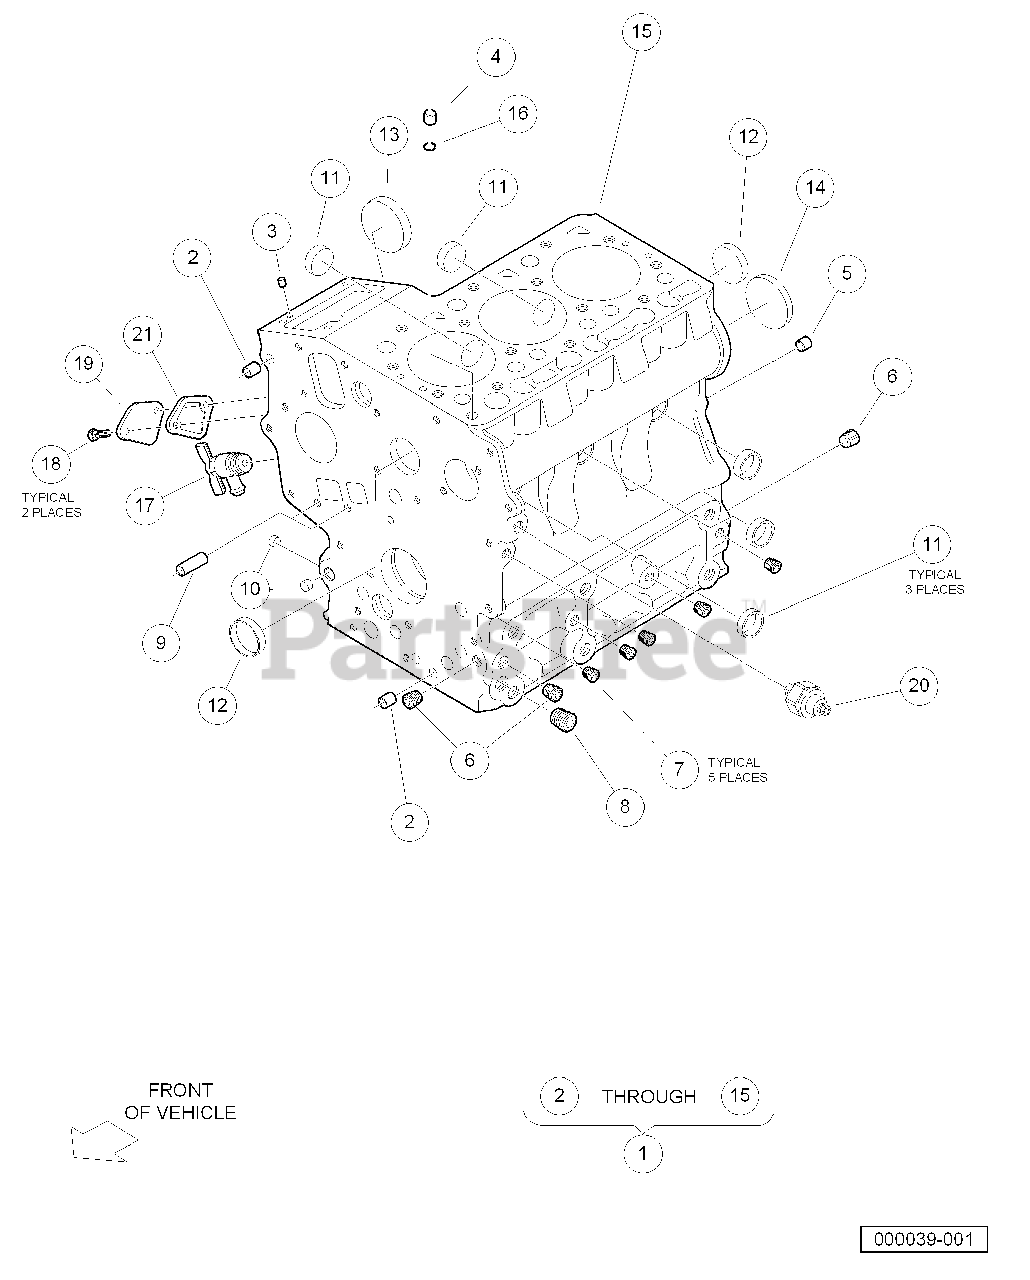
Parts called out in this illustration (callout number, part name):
1	Engine Block
2	Pin, Pipe, Dia 8 X 14
3	Pin, Straight, Dia 5 X 10
4	Pin, Pipe, Dia 7 X 14
5	Pin, Straight, Dia 8 X 16
6	Plug, 1/8"
7	Plug, 3/32"
8	Plug, 1/4"
9	Pin, Pipe, Dia 8 X 11
10	Cap, Sealing, Small
11	Cap, Sealing, Med
12	Cap, Sealing, Large
13	Cover, Fuel Camshaft
14	Plug, Expansion
15	Block, Engine
16	O Ring, 8 X 7
17	Cock, Drain
18	Bolt, M6 X 1 X 20
19	Plate, Engine Block
20	Switch, Oil Pressure
21	Gasket, Fuel Pump, D722
